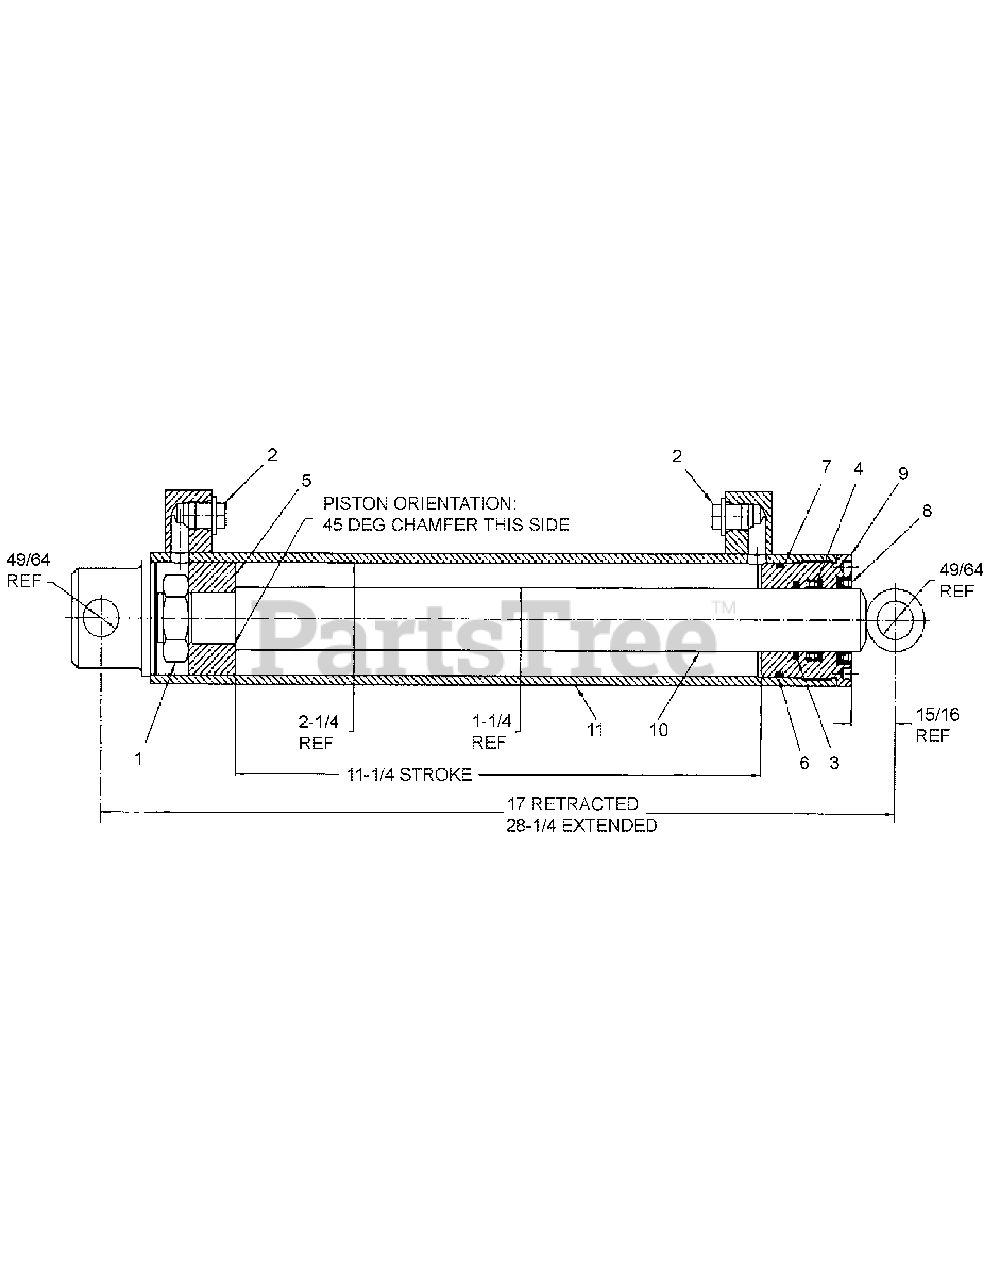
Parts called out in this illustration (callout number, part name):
1	NUT, 1'' NFJAM LOCK
3	STEP SEAL
4	U-CUP SEAL
6	O-RING
7	BACK-UP RING
8	ROD WIPER
9	THREADED GLAND
10	PISTON ROD WELDMENT
11	CYLINDER TUBE WELDMENT
